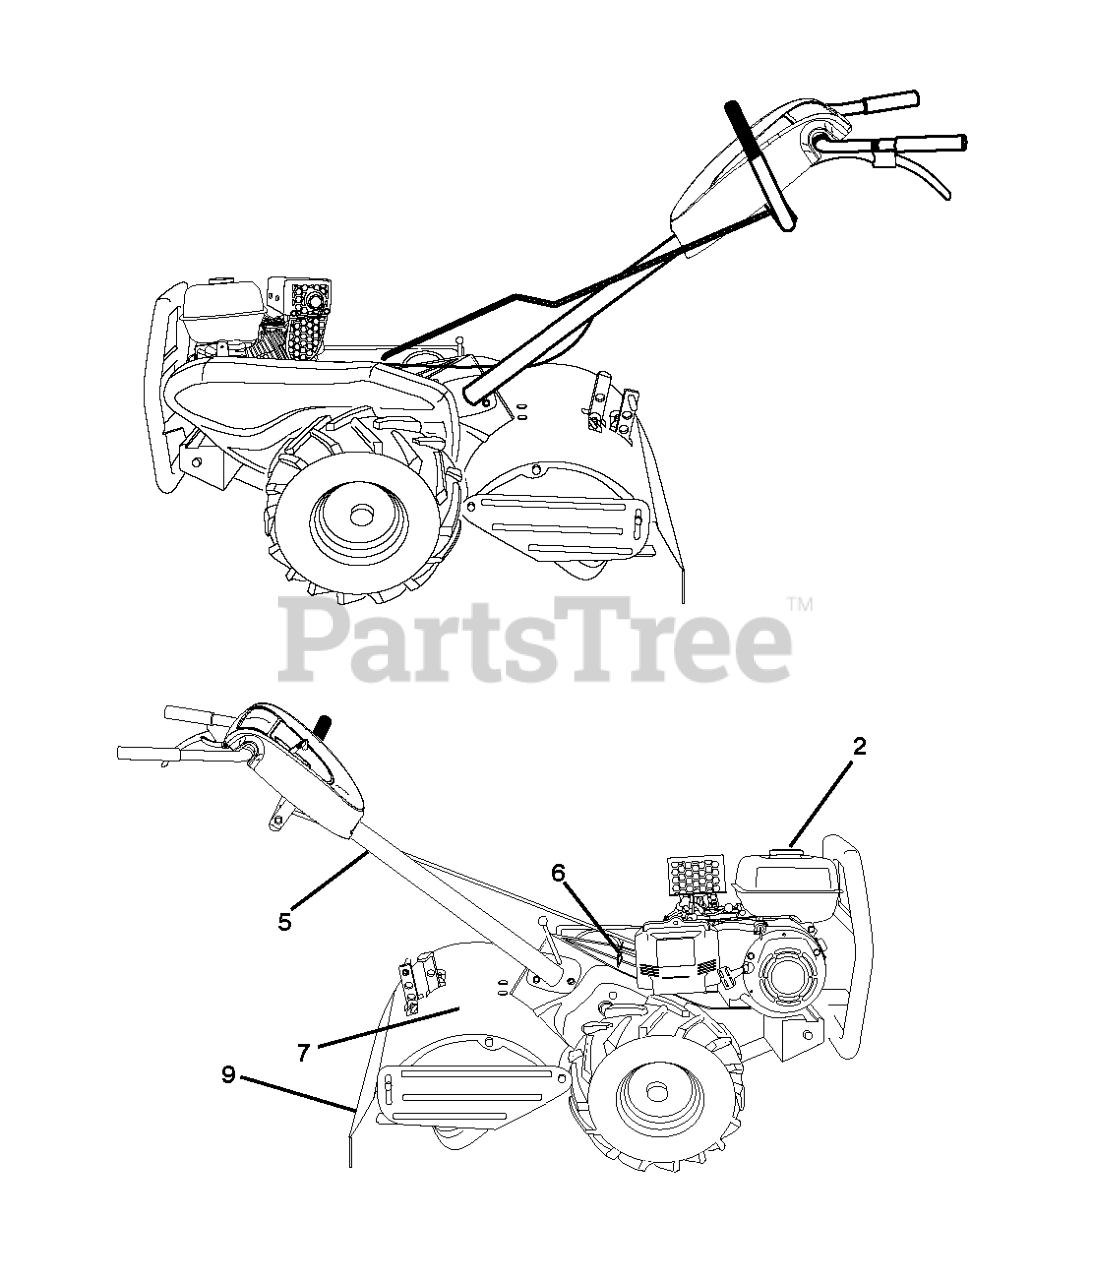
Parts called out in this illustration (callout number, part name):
2	DECAL.ETHANOL.E85 WARNING SYMB
5	DECAL TI (2 2)
6	DECAL.SHIFT.INDICATOR.DRT
7	DECAL TILLER TINE SHIELD GRAPH
9	DECAL.DRT.WARN.ENG/F
